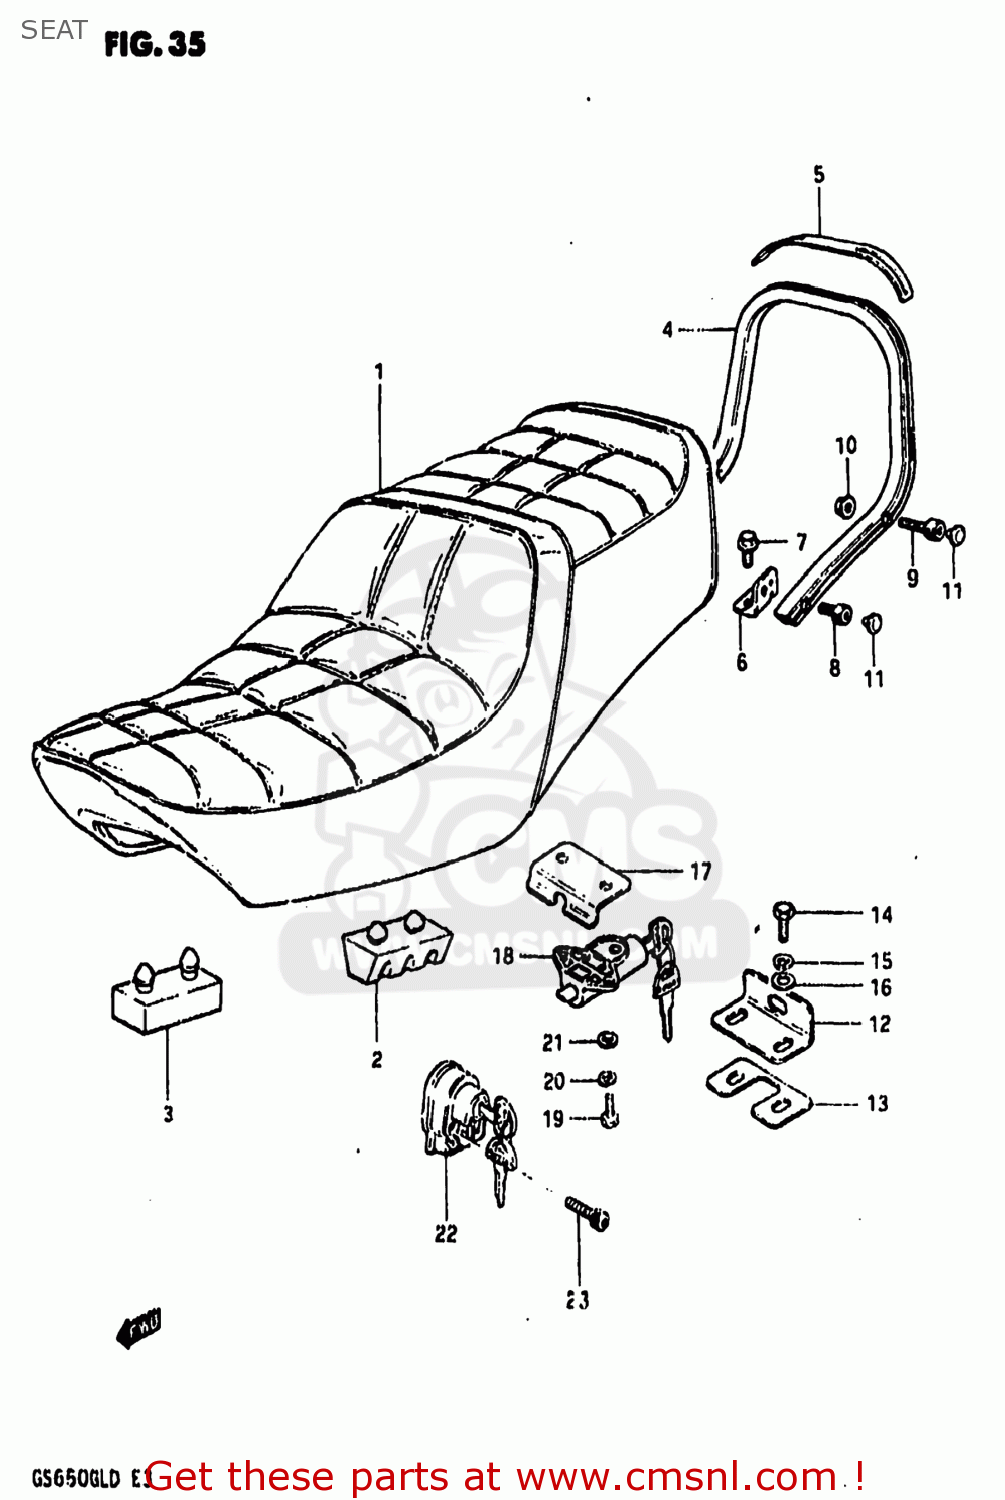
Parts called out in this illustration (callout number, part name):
1	SEAT ASSEMBLY
2	CUSHION,SUPPORT(50X25X32)
3	CUSHION
4	HANDLE,PILLION RIDER
5	RUBBER,PILLION RIDER HANDLE
7	BOLT 8X12
8	BOLT 8X16
9	BOLT
10	NUT
11	CAP(OD:14.5)
12	STRIKER, SEAT LOCK
13	SHIM,SEAT LOCK STRIKER
14	BOLT, UPPER
15	LOCK WASHER
16	WASHER
17	GUIDE, PLATE
18	LOCK ASSEMBLY,SEAT
19	BOLT
20	LOCK WASHER
21	WASHER
22	LOCK ASSY,HELMET
23	BOLT 5X25
